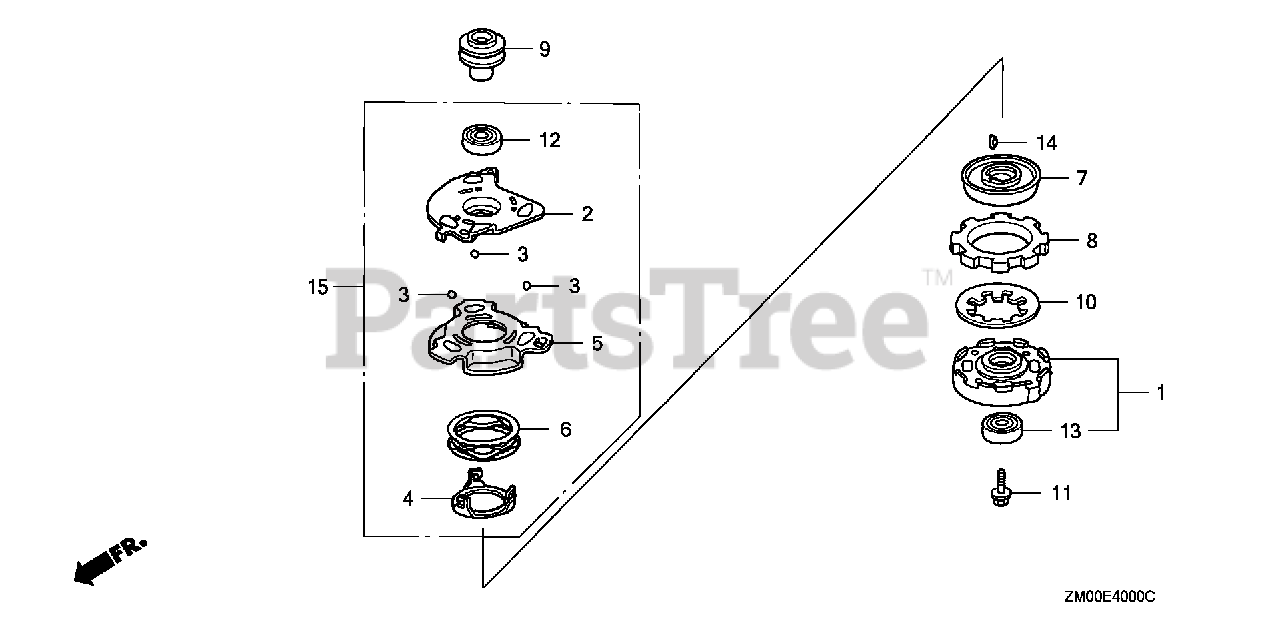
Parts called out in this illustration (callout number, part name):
1	HOLDER ASSY., BLADE
2	PLATE, BALL CONTROL
3	BALL, STEEL
4	PLATE, SPRING HOOK
5	PLATE, BRAKE
6	SPRING, BALL PLATE
7	DISK, DRIVE
8	DISK, DRIVEN
9	PULLEY, DRIVE
10	SPRING, CLUTCH
11	BOLT, FLANGE (10X24)
12	BEARING, RADIAL BALL (6006) (SST)
13	BEARING, RADIAL BALL (6204)
14	KEY, WOODRUFF (16X15)
15	PLATE ASSY., BALL CONTROL
